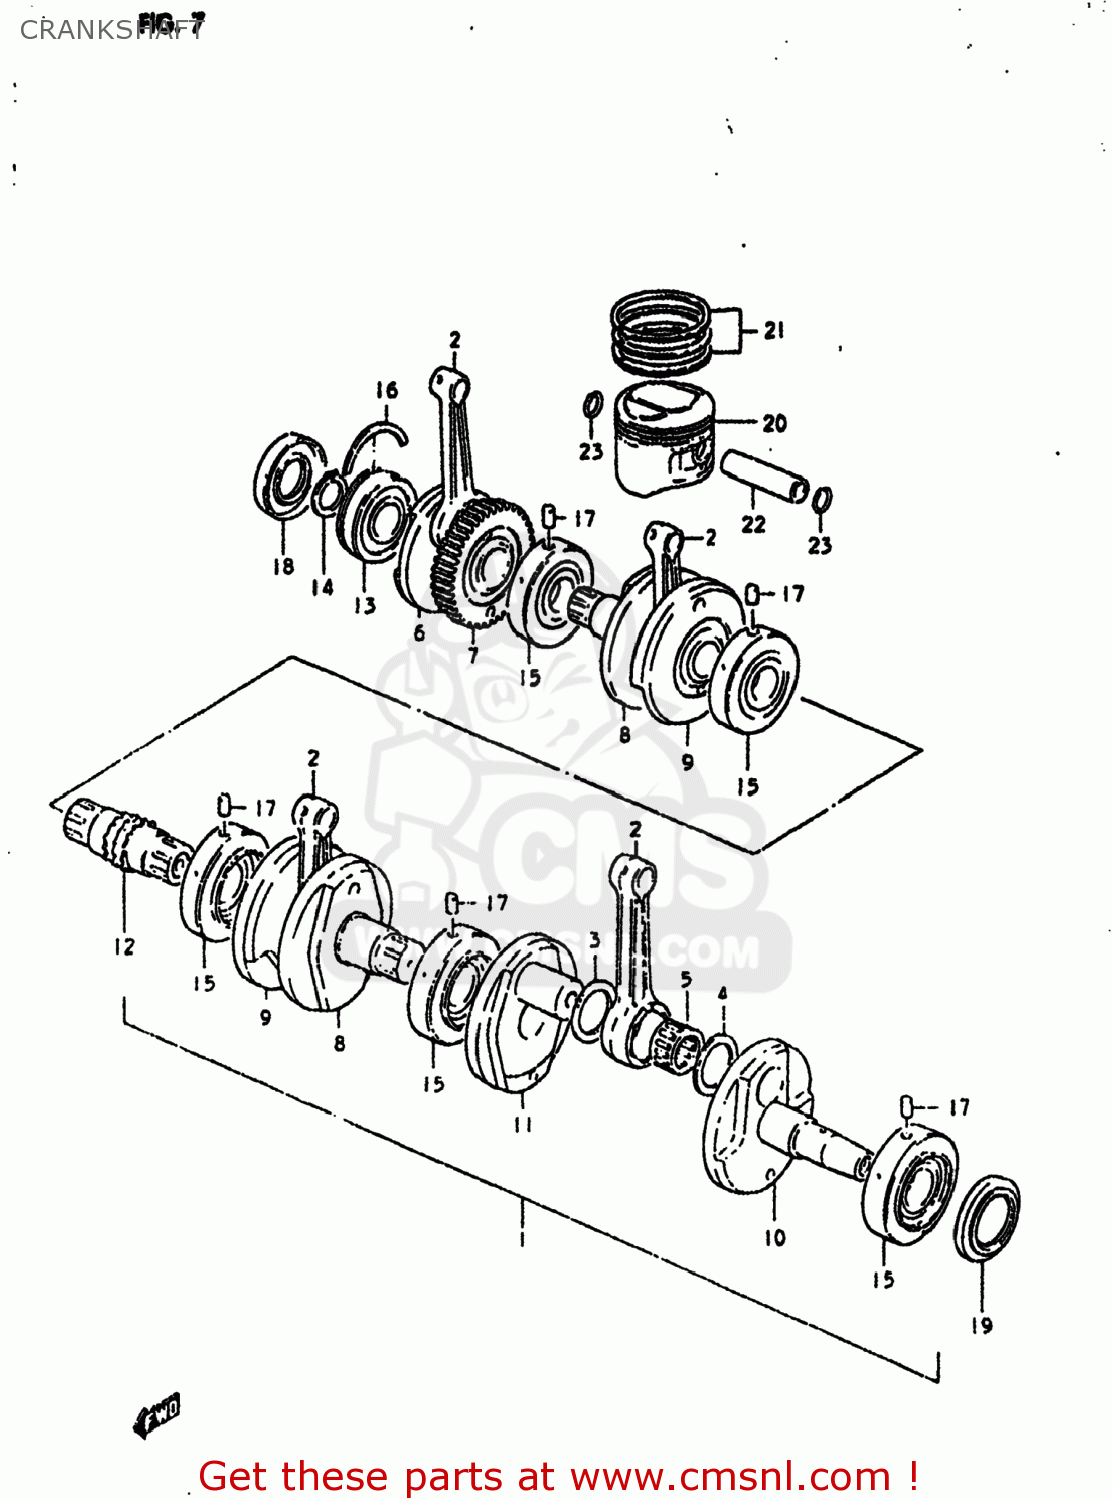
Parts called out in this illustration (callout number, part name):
1	CRANKSHAFT ASSEMBLY
2	ROD,CONNECTING
3	WASHER (28X48X2)
4	WASHER(28X48X1)
5	ROLLER BEARING (28X38X16.8)
6	CRANKSHAFT
7	WEB,CRANK
8	CRANKSHAFT
9	WEB,CRANK,MIDDLE
10	CRANKSHAFT,LEFT
11	WEB,CRANK,LEFT
12	SHAFT,TIMING CHAIN DRIVE
13	BEARING(30X72X19)
14	CIRCLIP,30MM
15	BEARING
16	C RING
17	PIN
18	SEAL,OIL(30X72X11)
19	OIL SEAL
20	PISTON
21	RING SET,PISTON
22	PIN,PISTON 16MM
23	CIRCLIP
